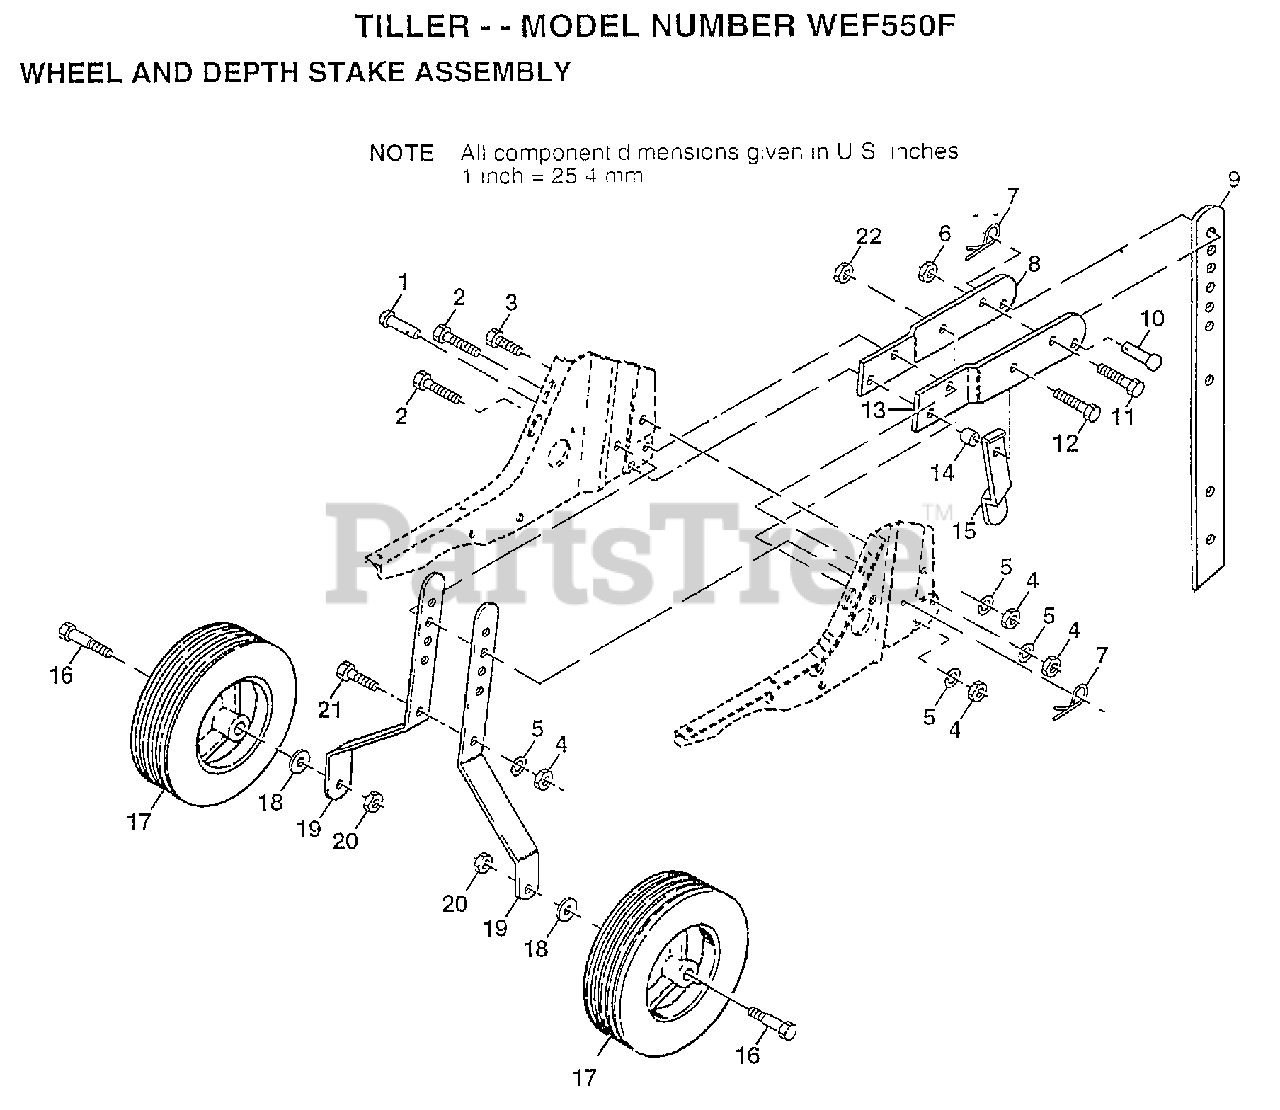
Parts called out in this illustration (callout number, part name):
1	DRILLED RIVET RT
3	BOLT
4	NUT.HEX.5/16-18
5	LOCKWASHER
6	NUT
7	SPRING.RETAINER
11	BOLT
12	BOLT.HEX.5/16-1.5
14	WASHER
15	STAKE SPRING TI
16	BOLT SHOULDER
17	WHEEL.8X1.75.YELL
18	WASHER
22	NUT
